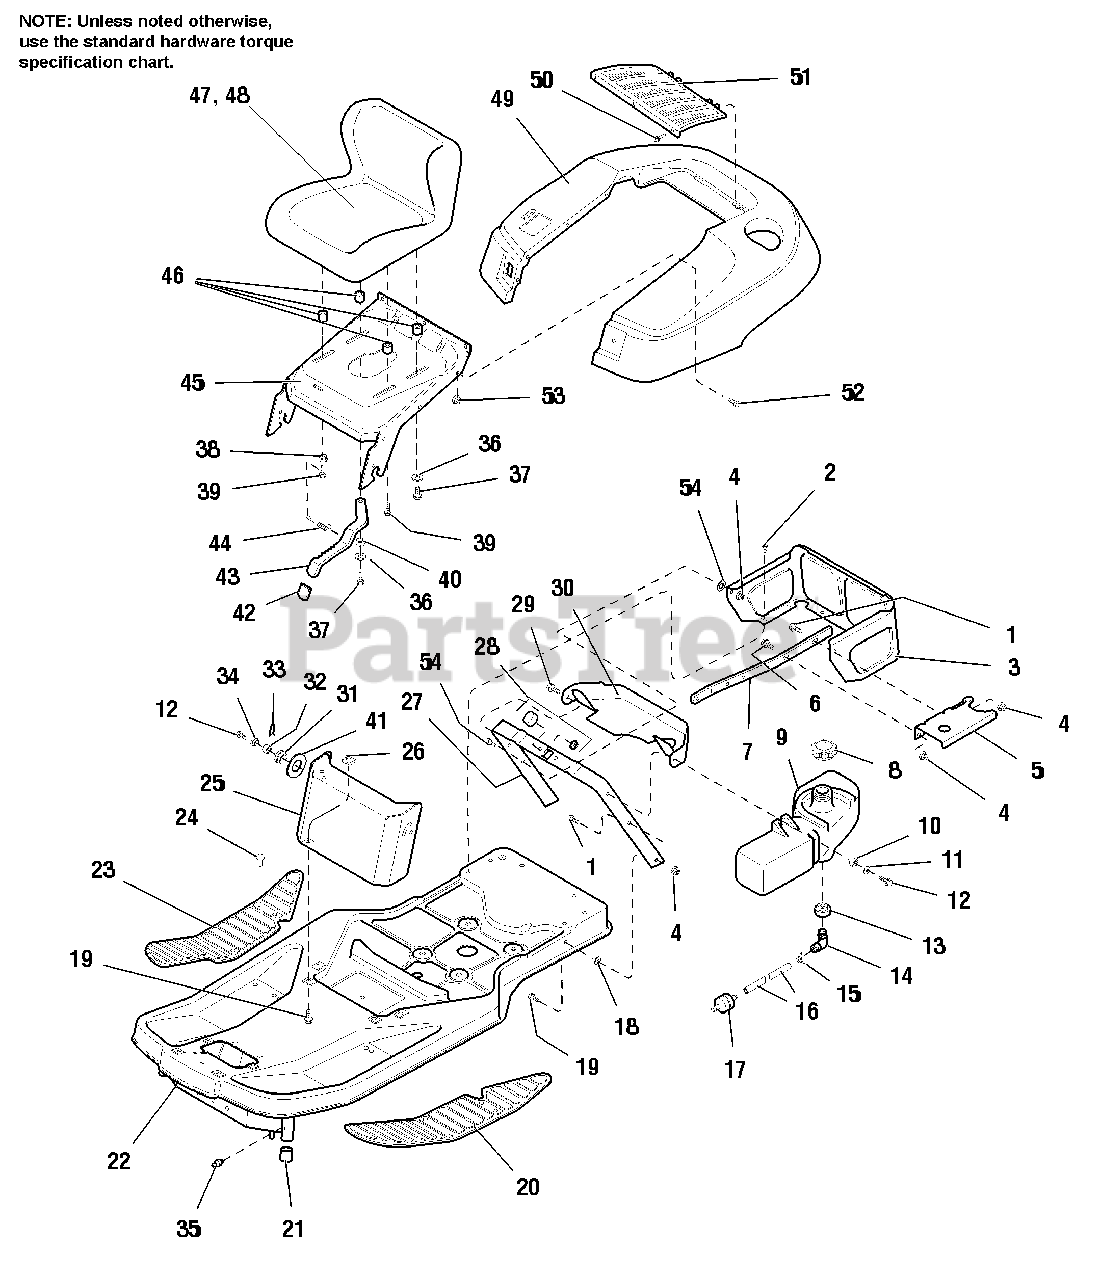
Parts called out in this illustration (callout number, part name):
1	CAPSCREW, Hex Hd., 5/16-18 x 1
2	SCREW, Hex Hd., Taptite, 1/4-20 x 1/2
3	SHROUD, Rear
4	NUT, Hex, Flange, Whizlock, 5/16-18
5	SUPPORT, Fuel Tank
6	CARRIAGE BOLT, 5/16-18 x 3/4
7	STRAP, Fuel Tank, Brace
8	CAP, Fuel Tank, Vented
10	SPACER, 21/64 x 1/2 x 21/64
11	WASHER, Plain, 13/32 x 7/8 x 5/64
12	SCREW, Taptite, 5/16-18 x 1
13	BUSHING, Rubber
15	CLAMP, Hose
16	HOSE, Fuel Line
17	FILTER, Fuel
18	PAL NUT, 5/16
19	CAPSCREW, Hex Hd., Whizlock, 5/16-18 x 3/4
20	PAD, Foot Rest, LH
22	FRAME ASSY.
23	PAD, Foot Rest, RH
25	PANEL, Front
26	PAL NUT, 5/16-18
27	SUPPORT, "U", Seat
28	BUMPER, Rubber
29	SCREW, Hex Hd., Taptite, 5/16 x 1/2
30	DUCT, Air Inlet
31	SPACER, Plastic
34	PIVOT, Hood
35	FITTING, Lube
36	WASHER, Plain
37	CAPSCREW, Hex Hd., 5/16-18
38	NUT, 5/16-18
39	CAPSCREW, 5/16-18 x 1-1/4
42	CAP, Black, Vinyl
43	ADJUSTER, Seat
44	SPRING, Extension
45	SUPPORT, Seat
47	SEAT ASSY.
48	COVER, Seat, Black
49	DECK, Seat, Orange
49	DECK, Seat, Red
51	SCREEN, Seat Deck Top
52	SCREW, Hex Whiz Lock
53	NUT, Flange, 1/4-20
54	WASHER, 5/16
